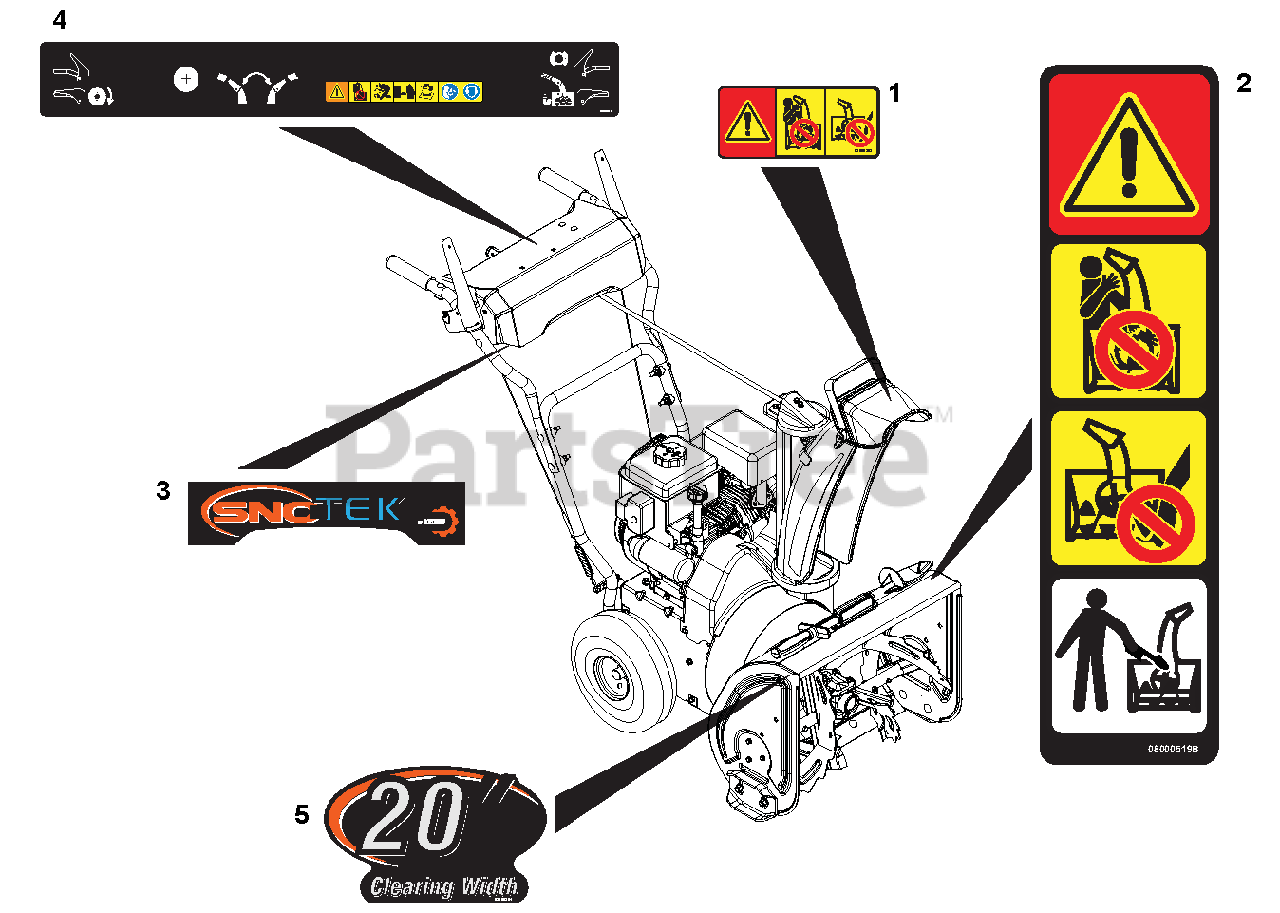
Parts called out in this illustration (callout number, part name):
1	DECAL, DANGER SNO-TEK
2	DECAL, DANGER - ROTATING PARTS
3	DECAL, DASH - SNO-TEK
4	DECAL, CONTROL - SINGLE SPEED
5	DECAL, HOUSING SNO-TEK 20
